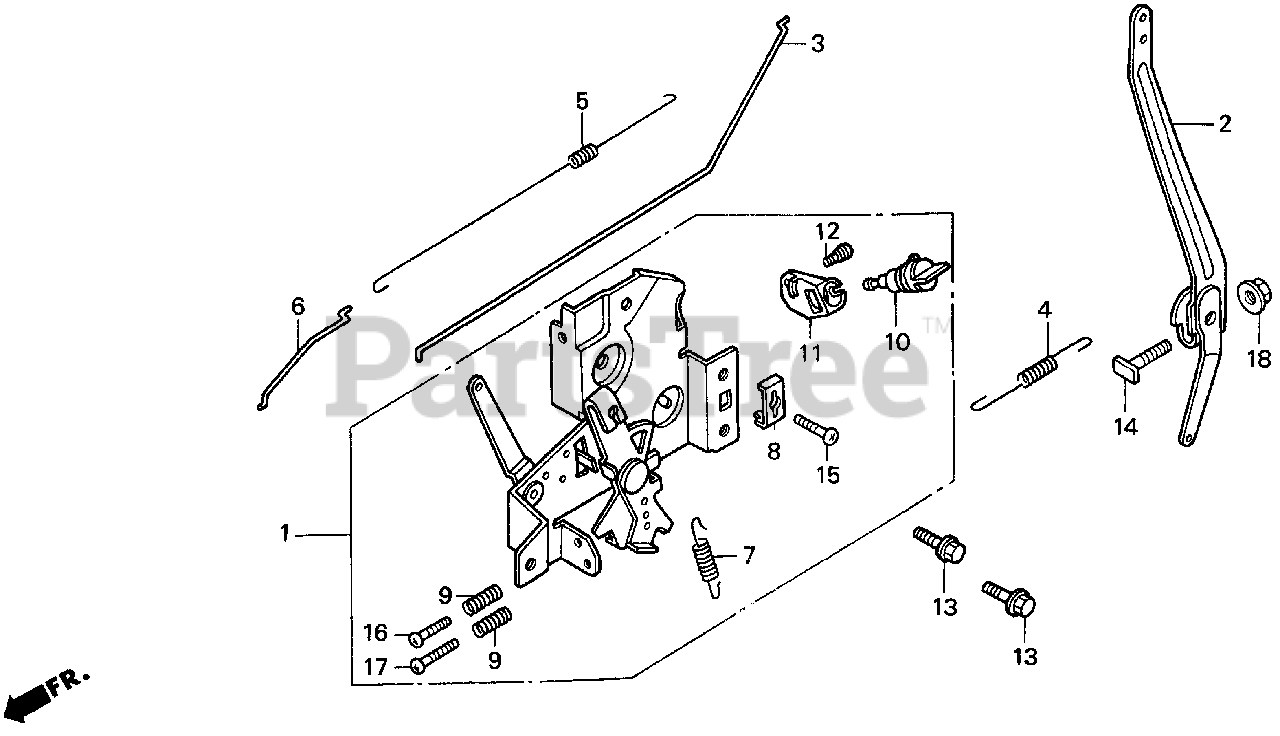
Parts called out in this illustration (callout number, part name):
1	CONTROL ASSY.
2	ARM, GOVERNOR
3	ROD, GOVERNOR
4	SPRING, GOVERNOR
5	SPRING, THROTTLE RETURN
6	ROD, CHOKE
7	SPRING, LEVER
8	HOLDER, CABLE
9	SPRING, CONTROL ADJUSTING Use from Engine SN 2327377.
10	PETCOCK ASSY.
11	BRACKET, PETCOCK
12	SCREW, SHOULDER (5X12)
13	BOLT, FLANGE (6X14)
14	BOLT, GOVERNOR ARM
15	SCREW, PAN (5X16)
16	SCREW, PAN (5X20)
17	SCREW, PAN (5X25)
18	NUT, FLANGE (6MM)
